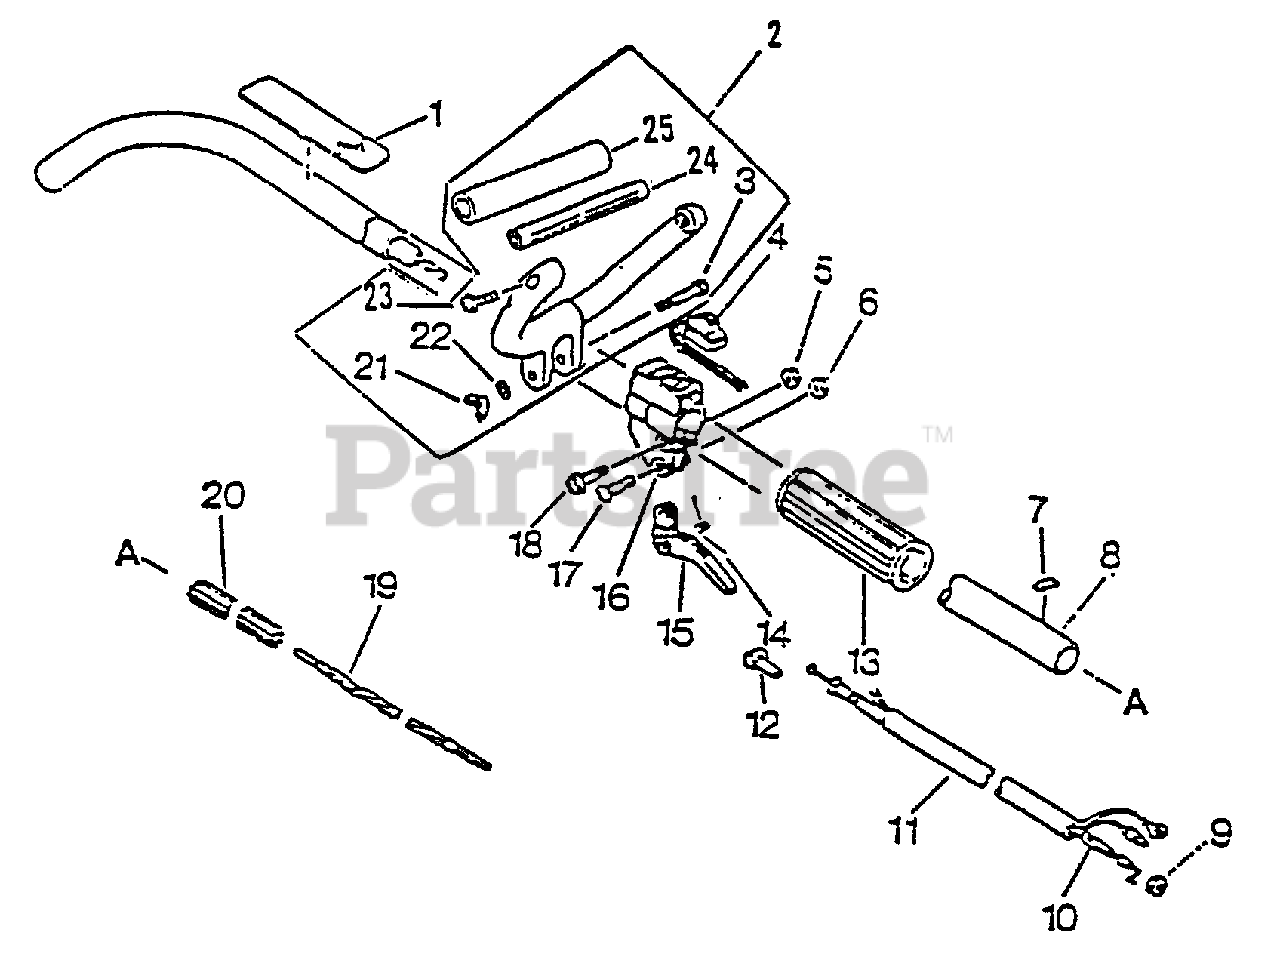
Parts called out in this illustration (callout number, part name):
1	LABEL - CAUTION
2	HANDLE
3	BOLT - 6×40
4	IGNITION SWITCH ASSY
5	NUT M5
6	NUT, LOCK M5
7	LABEL - ALIGNMENT
8	PIPE, MAIN
10	CABLE, THROTTLE
12	GUIDE, CABLE
14	SPRING, THROTTLE
15	TRIGGER, THROTTLE
16	BRACKET, THROTTLE CONTROL
18	SCREW 5×28
19	DRIVESHAFT - FLEXIBLE
20	LINER - FLEXIBLE
21	NUT, WING 6
22	WASHER 6.5×11.5×0.8
23	SCREW 5×30
24	HANDLE, FRONT
25	GRIP, HANDLE
